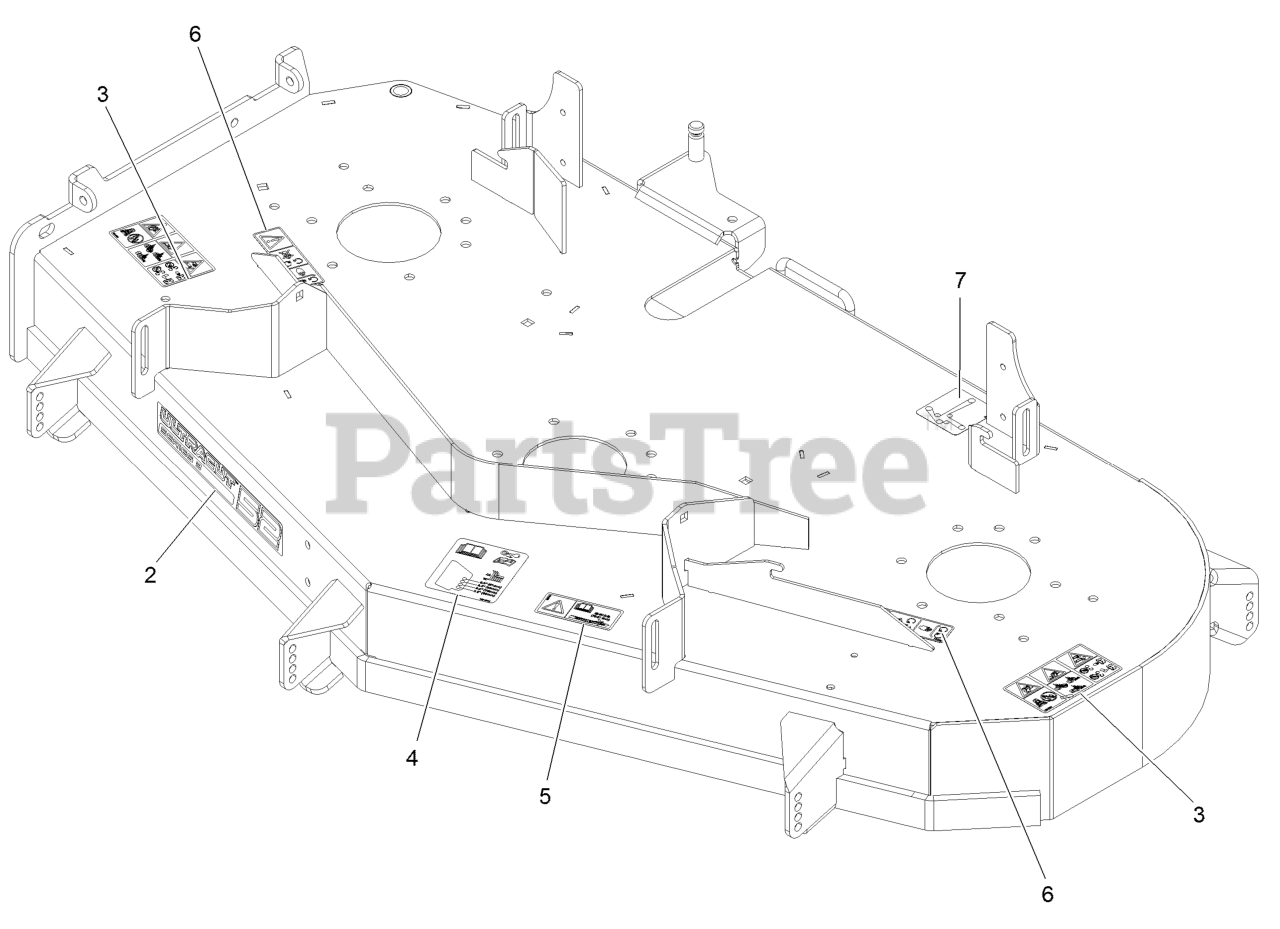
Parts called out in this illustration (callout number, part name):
2	DECAL-ULTRACUT 52 SERIES
3	DECAL-DANGER THROWN OBJECTS
4	DECAL-ROLLER, ANTI-SCALP
5	DECAL-BOLT TORQUE
6	DECAL-COVER, MISSING
7	DECAL-ROUTING, BELT
